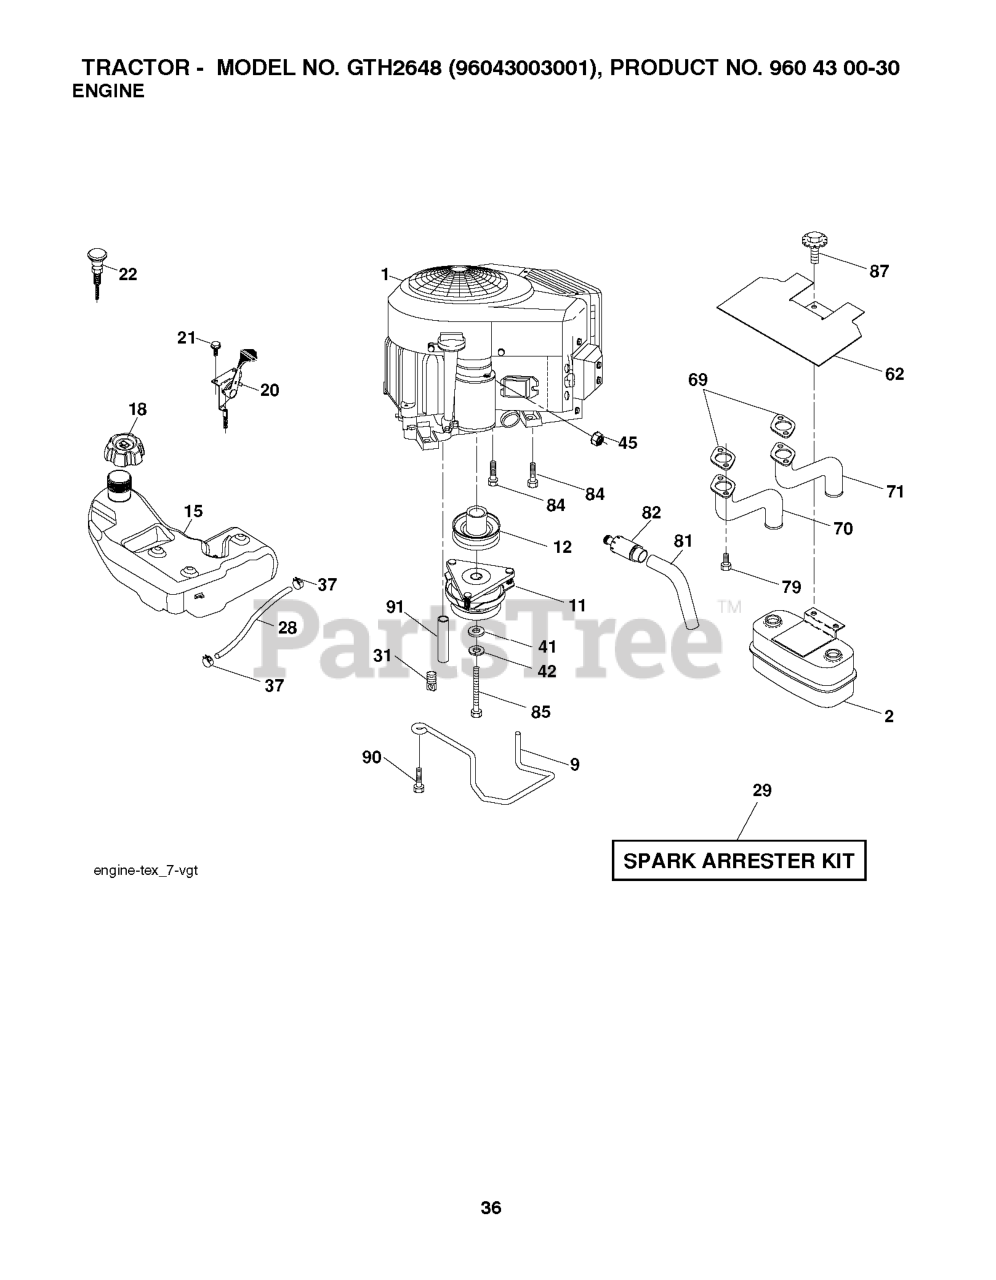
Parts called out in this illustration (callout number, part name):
2	MUFFLER.TWIN.CYL.LOW.TONE
9	KEEPER.BELT.ENGINE.4.2
11	CLUTCH MZ ZTR GT.48/54"1.125"
12	PULLEY ENGINE
15	TANK.FUEL.4GAL
18	CAP.FUEL.TANK.3"GREY
20	THROTTLE CABLE
21	SCREW.#10 X 0.750.BOS
22	CONTROL.CHOKE.ERGO.PUSH-IN.BLA
28	LINE.FUEL.64"REAR.EMIS
29	KIT.SPARK ARRESTOR 794945 B&S
37	HOSE CLAMP
42	LOCKWASHER
45	NUT
62	RP SHIELD HEAT MUFFLER
69	GASKET.MUFFLER
70	RP.EXHAUST.TUBE.LH.BS/TWIN
71	EXHAUST.TUBE.RH.BS/TWIN
79	SCREW.SOCKET.HEAD.5/16-18
81	TUBE, DRAIN OIL ASM.
82	PLUG DRAIN OIL EASY
84	SCREW.3/8-16
85	BOLT HEX 7/16-20 X 3.75 GR. 5
87	BOLT.5/16-18UNCX1.W/SEMS.BLK
90	SCREW 3/8-16X1
91	BUSHING.1.375OD
